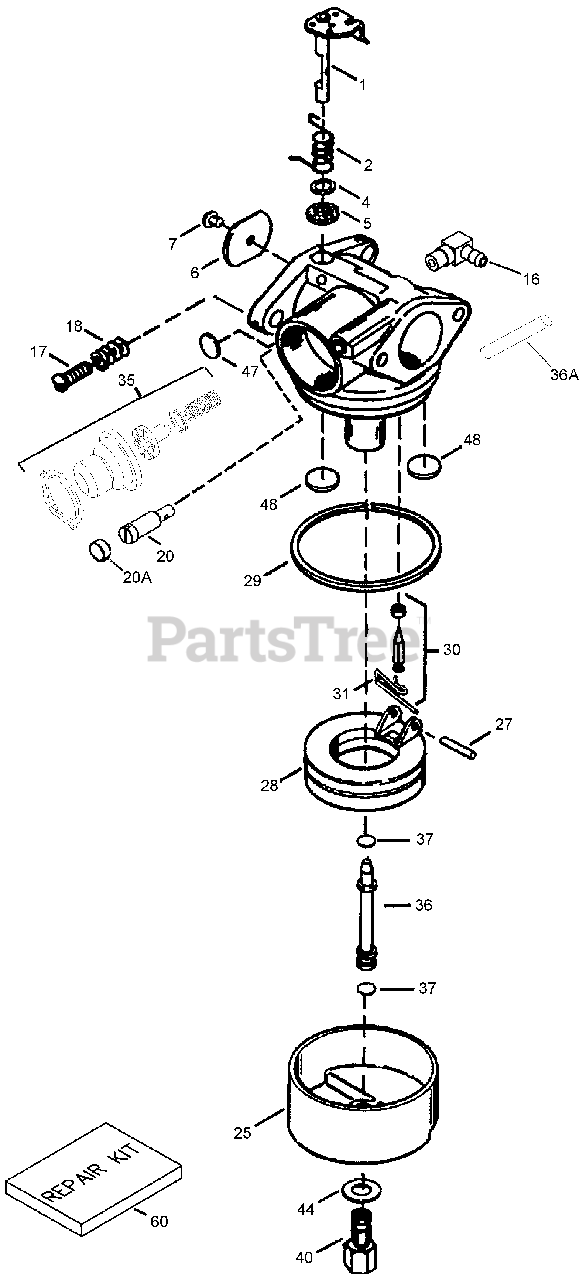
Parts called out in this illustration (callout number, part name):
1	Throttle Shaft and Lever ASM
2	Spring-Return, Throttle
4	Washer-Seal, Dust
5	Seal-Dust, Throttle
6	Shutter-Throttle
7	Screw-Shutter
16	Fitting-Fuel
17	Screw-Throttle/Idle Speed
18	Spring-Tension
20	Screw-Restrictor, Idle
20A	Cap-Screw, Idle Restrictor
25	Bowl-Float
27	Shaft-Float
28	Float (Plastic)
29	O Ring-Bowl, Float
30	Inlet Needle, Seat, and Clip ASM (Includes 31)
31	Clip-Spring
35	Primer Bulb/Valve Repair Kit
36	Tube-Nozzle, Main
36A	Tube-Carburetor
37	O Ring-Tube, Main Nozzle
40	Nut-Bowl, High Speed
44	Washer-Bowl
47	Welch Plug-Idle Mixture Well
48	Welch Plug-Atmospheric Vent
60	Repair kit
